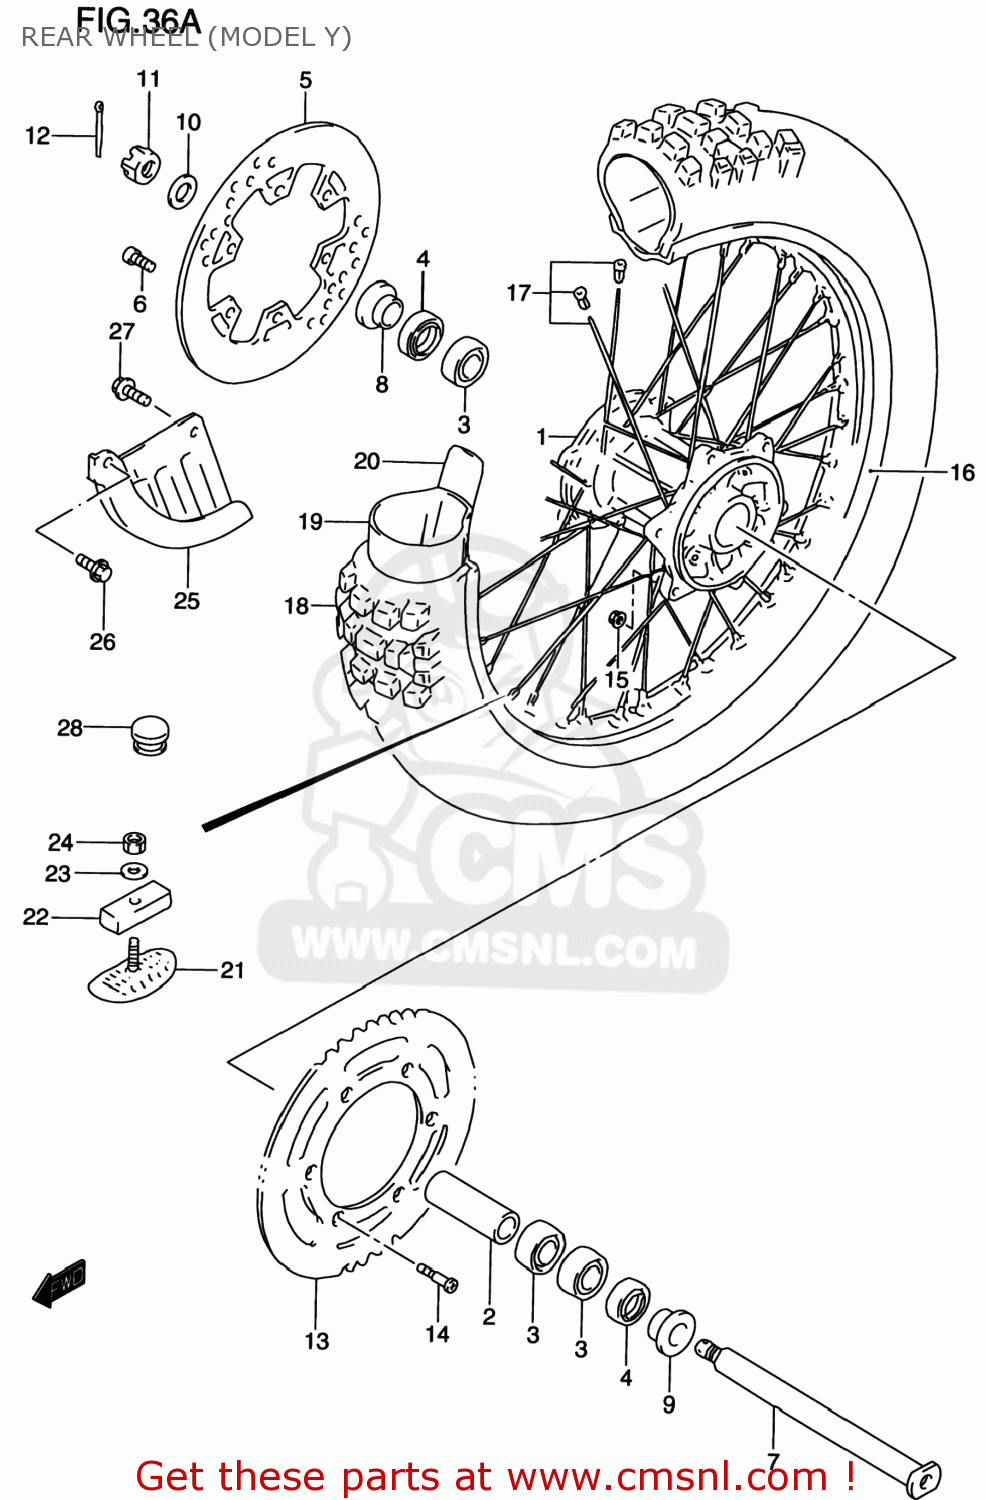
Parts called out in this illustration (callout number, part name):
1	HUB,RR WHEEL
2	SPACER,RR HUB BEARING
3	BEARING(22X44X12)
4	SEAL,OIL(30X44X7)
5	DISC,RR BRAKE
6	SCREW
7	AXLE,RR
8	SPACER,RR AXLE
9	SPACER,RR AXLE
10	WASHER(19X32X3.2)
11	NUT
12	PIN,COTTER
13	SPROCKET,RR(NT:48)
14	BOLT(8X30.5)
15	NUT
16	RIM,RR WHEEL(2.15X19 AL.)
17	SPOKE SET,RR WHEEL
18	TIRE,REAR 110/90-19
19	TUBE ASSY,WHEEL INNER
20	PROTECTOR,WHL INR TUBE
21	STOPPER,BEAD(2.15)
22	CUSHION,BEAD STOPPER
23	WASHER
24	NUT
25	COVER,REAR DISC
26	BOLT
27	BOLT
28	CAP(OD:12)
